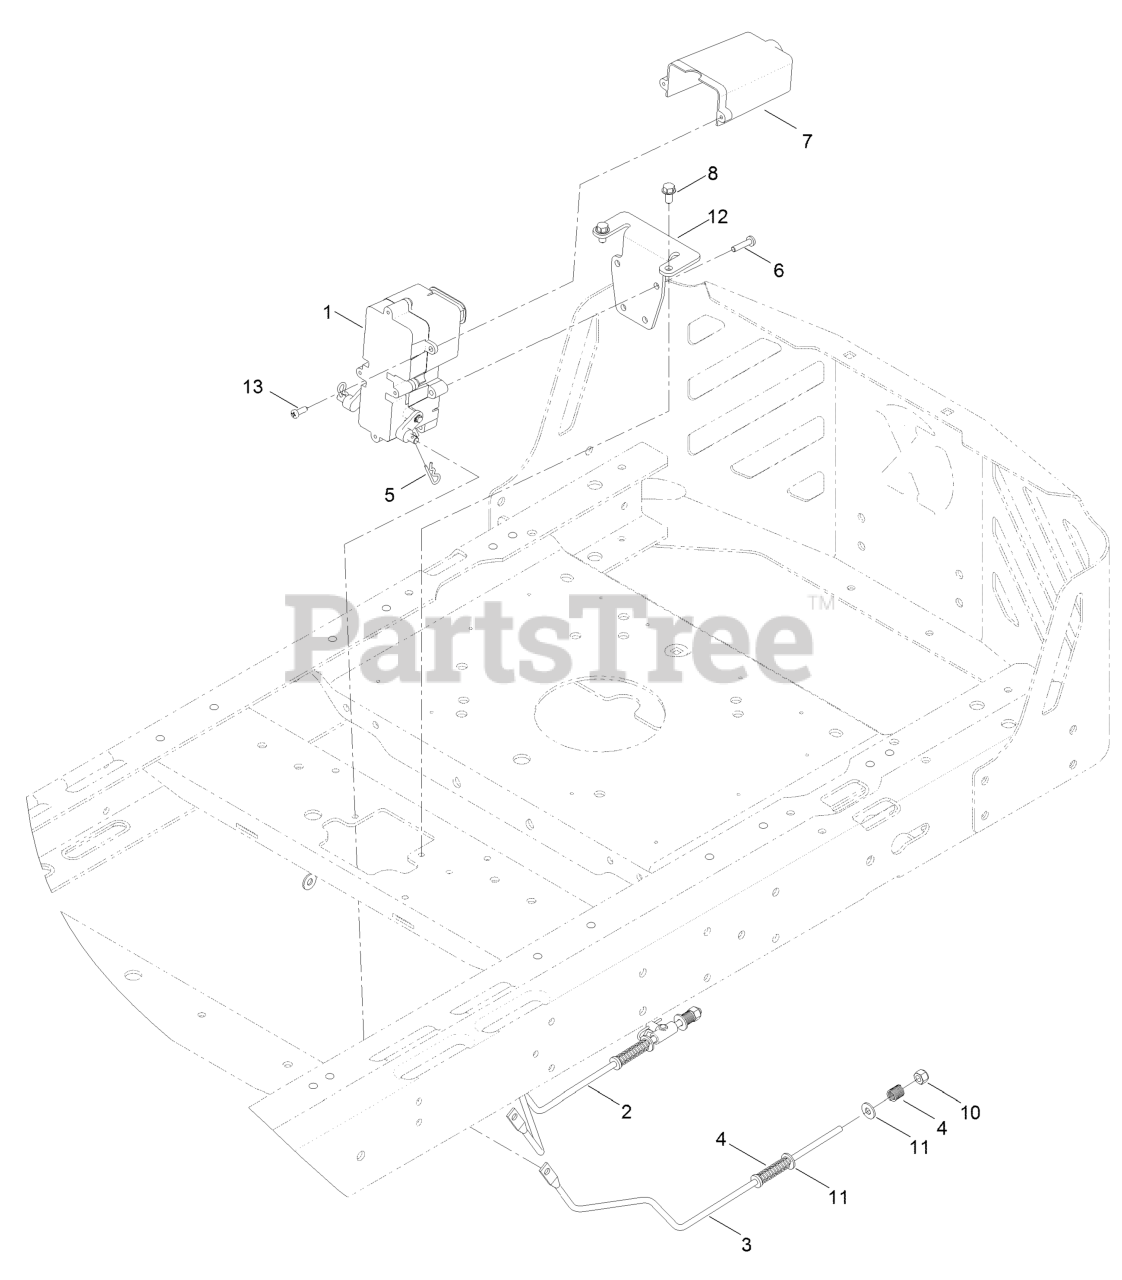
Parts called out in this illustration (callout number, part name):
2	ROD-BRAKE, WIDE (RH)
3	ROD-BRAKE, WIDE (LH)
4	SPRING-COMPRESSION
6	SCREW-PPH
8	SCREW-HWH
10	NUT-LOCK, NI
12	BRACKET-MOUNT, BRAKE
13	SCREW-PPH
